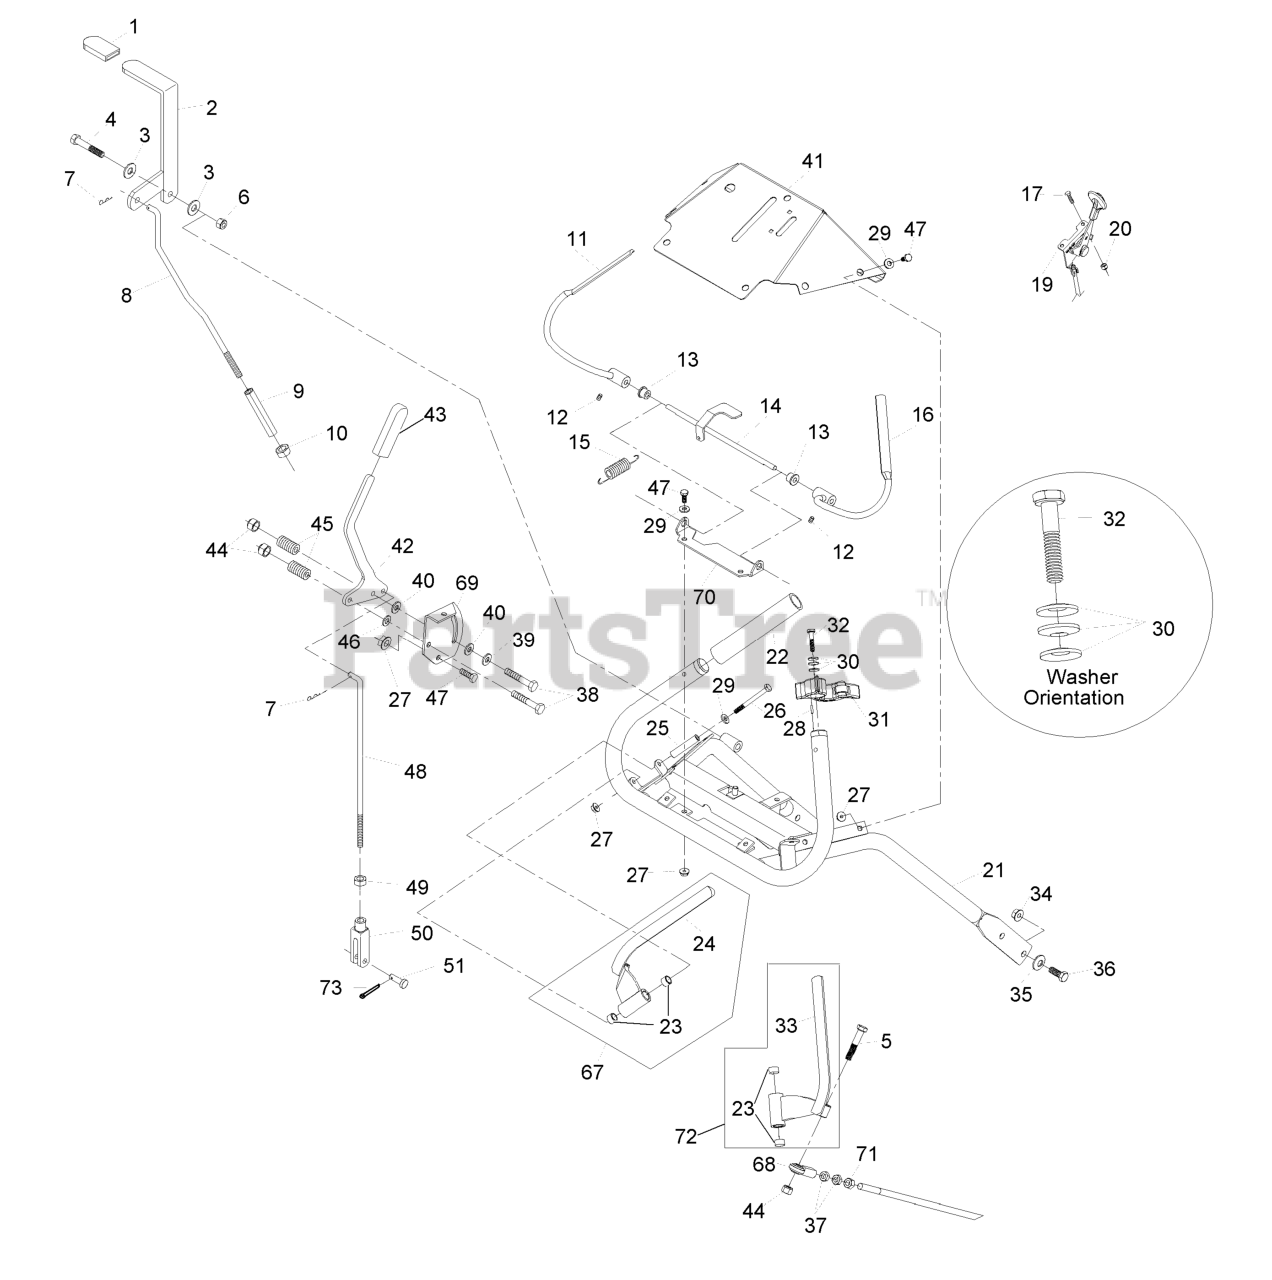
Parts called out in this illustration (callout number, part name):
1	GRIP-LEVER
2	ASM, LEVER W/GRIP
3	WASHER-FLAT
4	SCREW-HH
5	SCREW-HH
6	NUT-LOCK, NI
7	PIN-COTTER
8	LINK,BLADE ENGAGE (PLTD)
9	TURNBUCKLE
10	NUT-HEX
11	WLD,LH OPC LEVER
12	SCREW-SET
13	BUSHING-NYLON
14	WLD,OPC LEVER AXLE
15	SPRING-EXTENSION
16	WLD,RH OPC LEVER
17	BOLT-CARR
19	CONTROL, THROTTLE
20	NUT-LOCK, NI
21	WLD,UPPER ECS HANDLE
22	GRIP-BAR, HANDLE
23	BUSHING-SLEEVE
24	Lever, Drive Lh
25	BUSHING-LEVER, DRIVE
26	SCREW-HH
29	WASHER-FLAT
30	WASHER-SPRING
31	ASM,LATCH RH THUMB
31	ASM,LATCH LH THUMB
32	SCREW-HH
33	Lever, Drive Rh
34	NUT-HHF, WHIZ
35	WASHER-BELLEVILLE
36	SCREW-HH
37	NUT-HJ
38	SCREW-HH
39	WASHER-FRICTION
40	WASHER-FRICTION
41	ASM, CONSOLE W/ DECAL
42	LEVER, SHIFT W/GRIP
43	GRIP-HANDLE, STEERING
44	NUT-LOCK, NI
45	SPRING-COMPRESSION
46	WASHER-PLAIN
47	SCREW-HH
48	ROD,SPEED CONTROL
49	NUT-JAM
50	YOKE-ADJUSTABLE
51	PIN-CLEVIS
67	DRIVE LEVER-ASM, RH
68	JOINT-BALL, END
69	BRACKET,SHIFTER SLIDE (PL
70	BRACKET,OPC AXLE
71	NUT-HEX
72	DRIVE LEVER-ASM, LH
73	PIN-COTTER
